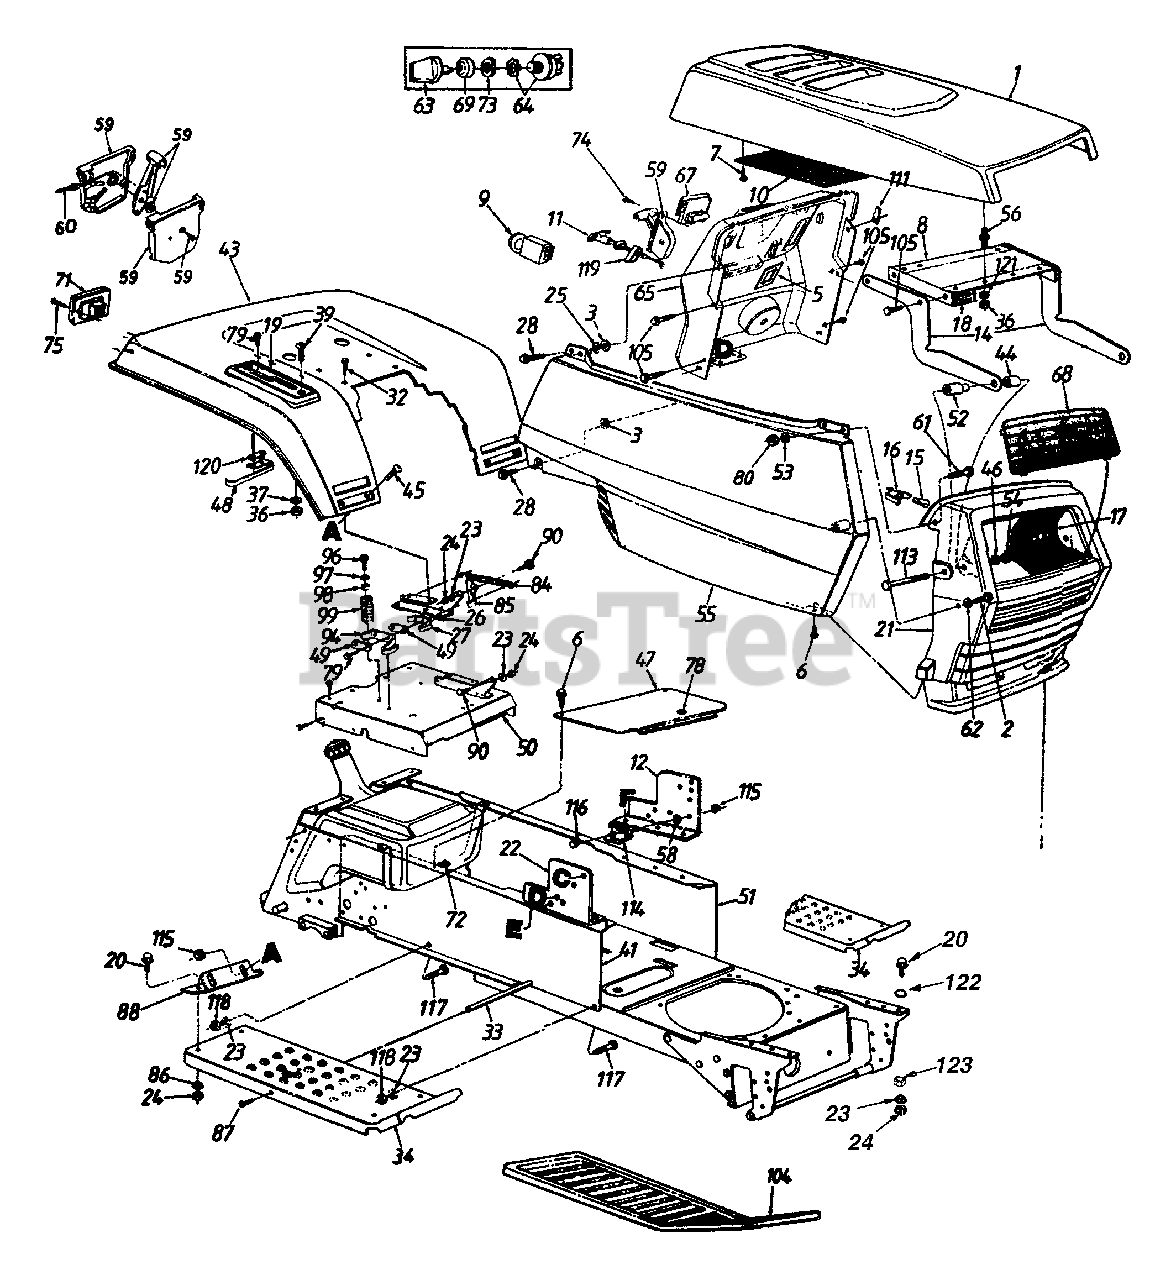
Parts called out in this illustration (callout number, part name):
2	Hex Wash. B-Tap Scr. 1/4 x .62" Lg.
3	Bolt Retainer 1/4" I.D.
5	Switch Retainer
6	Truss Mach. B-Tap Scr. #10 x .5" Lg.
7	Hex Wash. Hd. AB-Tap Scr. #8 x .5"
11	Choke Control
16	Twist Lock - Lamp Socket
17	Reflector - Headlight
19	Speed Control Index Brkt.
20	Hex Bolt 5/16-18 x .75" Lg.
21	Grille
24	Hex Sems Nut 5/16-18 Thd.
25	Fl-Wash. 1/4" I.D. x .93" O.D.
26	Insulator Boss Plate
27	Seat Spring Switch
28	Hex Wash. TT-Tap Scr. 1/4-20 x .75"
32	Hex Wash. Hd. AB-Tap Scr.
33	Running Board Rod
37	L-Wash. 1/4" I.D.
39	Truss Mach. Scr. 1/4-20 x 1.0" Lg.
44	Spacer .33" I.D. x .625" O.D.
45	Carriage Bolt 1/4-20 x .50" Lg.
46	Fl-Wash. .328" I.D. x .68" O.D.
49	Insulator Plate
50	Seat Plate
53	Fl-Wash. .281" I.D. x .5" O.D.
54	Hex Cent. L-Nut 5/16-18 Thd.
55	Side Cover Ass'y. - R.H.
56	Double Ended Stud 1/4-20 Thd.
58	Ext. L-Wash. 1/4" I.D.
59	Throttle Control Box Ass'y.
60	Throttle Control Wire 39" Lg.
61	Hex Bolt 1/4-20 x .62" Lg.
62	Fl-Wash. .281" I.D. x .73" O.D.
64	Ignition Switch
67	Ammeter
68	Lens
69	Ignition Switch Cap
71	Taillight Ass'y.
72	Speed Nut #10Z
73	Ignition Switch Nut
74	Truss Mach. AB-Tap Scr. #10 x .5" Lg.
75	Truss Hd. AB-Tap Scr. #6 x .62"
78	Snap Bushing
79	Hex Wash. Hd. AB-Tap Scr. #8 x .50"
80	Hex L-Nut 1/4-20 Thd.
84	Ext. Spring 5.31" Lg.
85	Seat Lift Brkt.
86	Bell-Wash. .345" I.D. x .88" O.D.
87	Truss Machine Scr. 5/16-18 x .75" Lg.
94	Spring Switch
96	Hex Flange TT-Scr. 5/16-18 x .875"
97	Fl-Wash. 5/16" I.D.
99	Compression Spring
105	Hex Tap Scr. 1/4-20 x .5" Lg.
111	Speed Nut 1/4-20 Thd.
113	Hex Bolt 5/16-18 x 2.75"
114	Solenoid
115	Hex Sems Nut 1/4-20 Thd.
116	Hex Bolt 1/4-20 x .5" Lg.
117	Rib Neck Bolt 5/16-24 x .75" Lg.
118	Hex Nut 5/16-24 Thd.
119	Retainer Clip
120	Insulator Nut Plate
121	Bell-Wash. .265" I.D. x .75" O.D.
122	Fl-Wash. .349" I.D. x 1" O.D.
123	Speed Nut .312" I.D.
